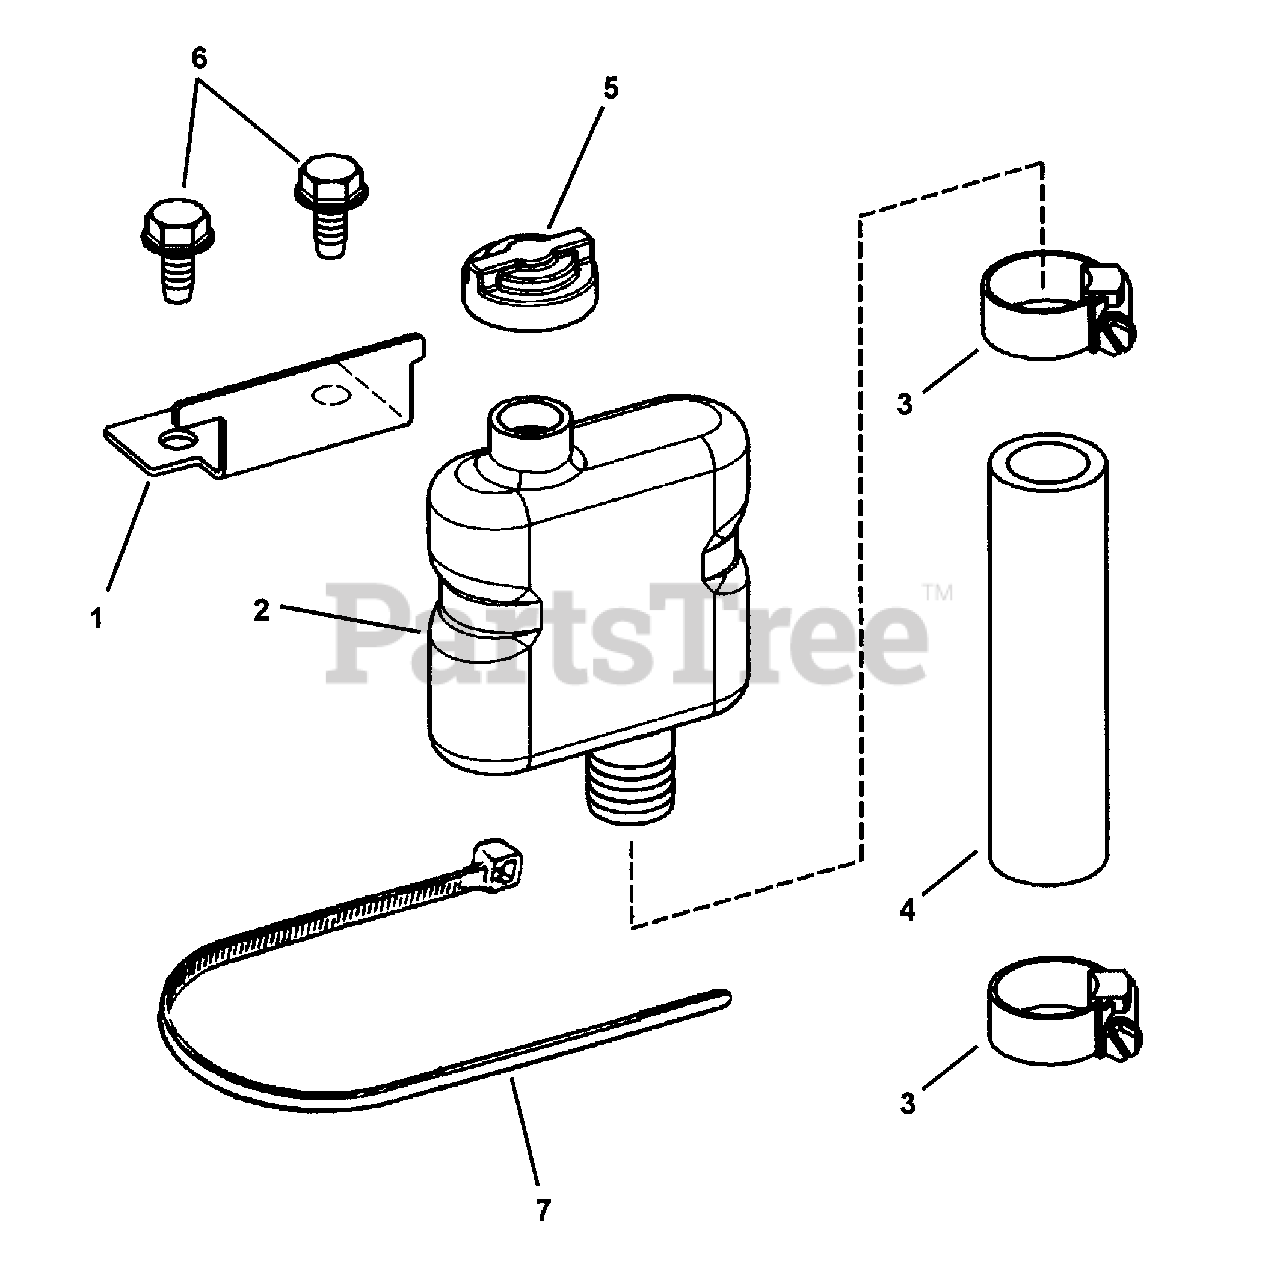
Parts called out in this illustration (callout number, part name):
1	BRACKET, Reservoir Mounting
2	RESERVOIR, Expansion
3	CLAMP, 13/16"
4	HOSE, Hydraulic 4-1/2" Long
5	VALVE, Vent
6	BOLT, 5/16-18 x 1/2" Hex Washer Self-Tap
7	CABLE TIE, 9"
